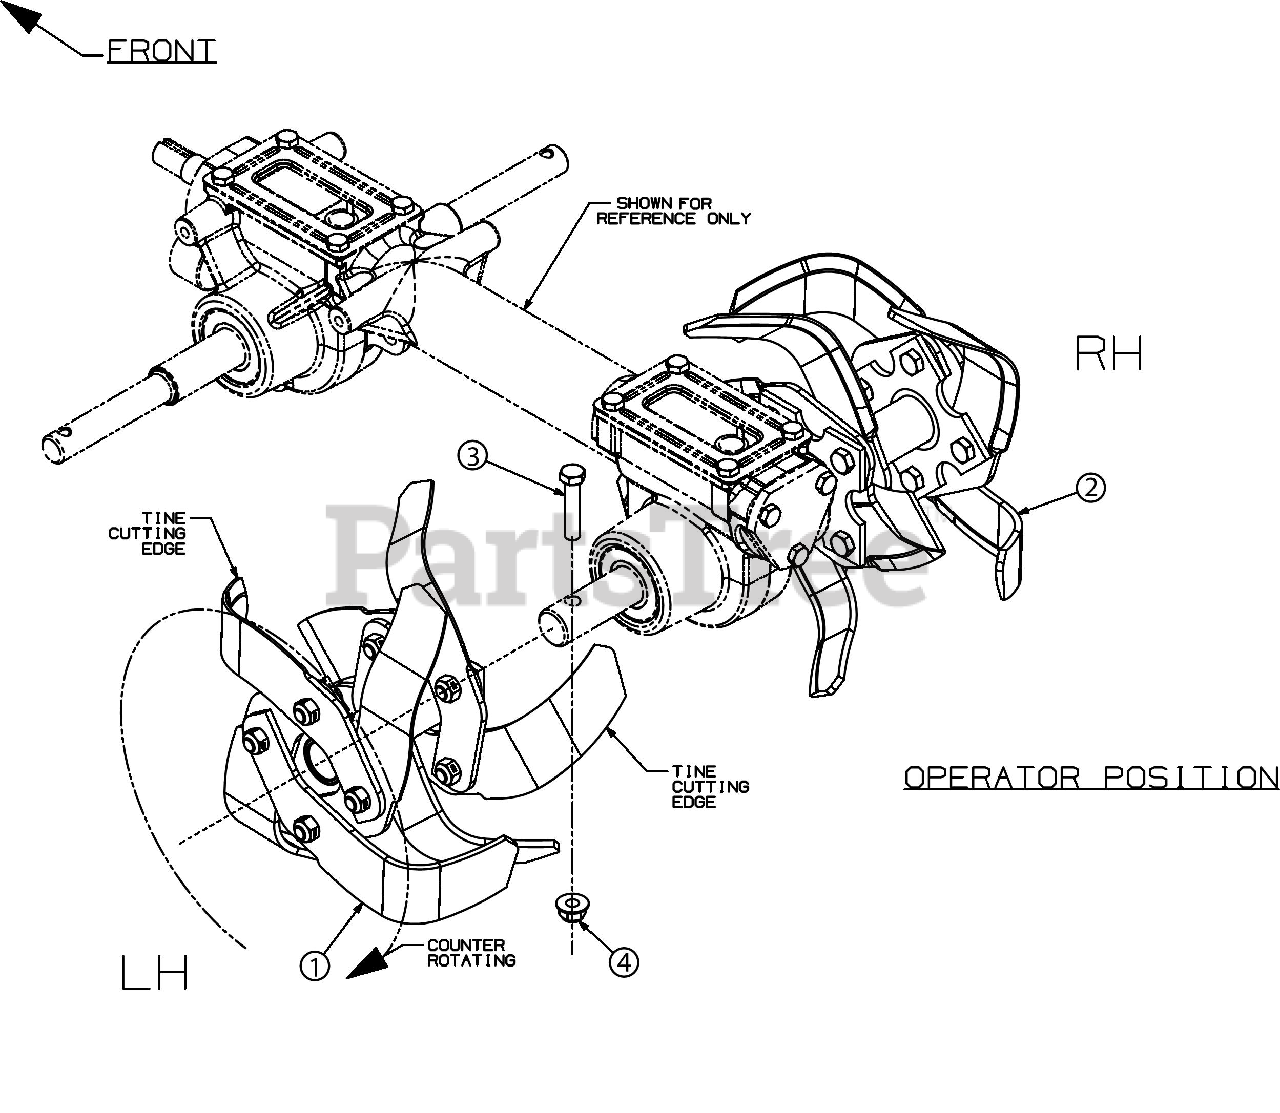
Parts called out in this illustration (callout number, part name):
1	TINE HOLDER ASSEMBLY
1	SCREW 3/8-16 x 1 GR5
1	LOCK NUT 3/8-16
2	TINE HOLDER ASSEMBLY
2	SCREW 3/8-16 x 1 GR5
2	LOCK NUT 3/8-16
3	HEX SCREW 3/8-16 x 1.75 GR5
